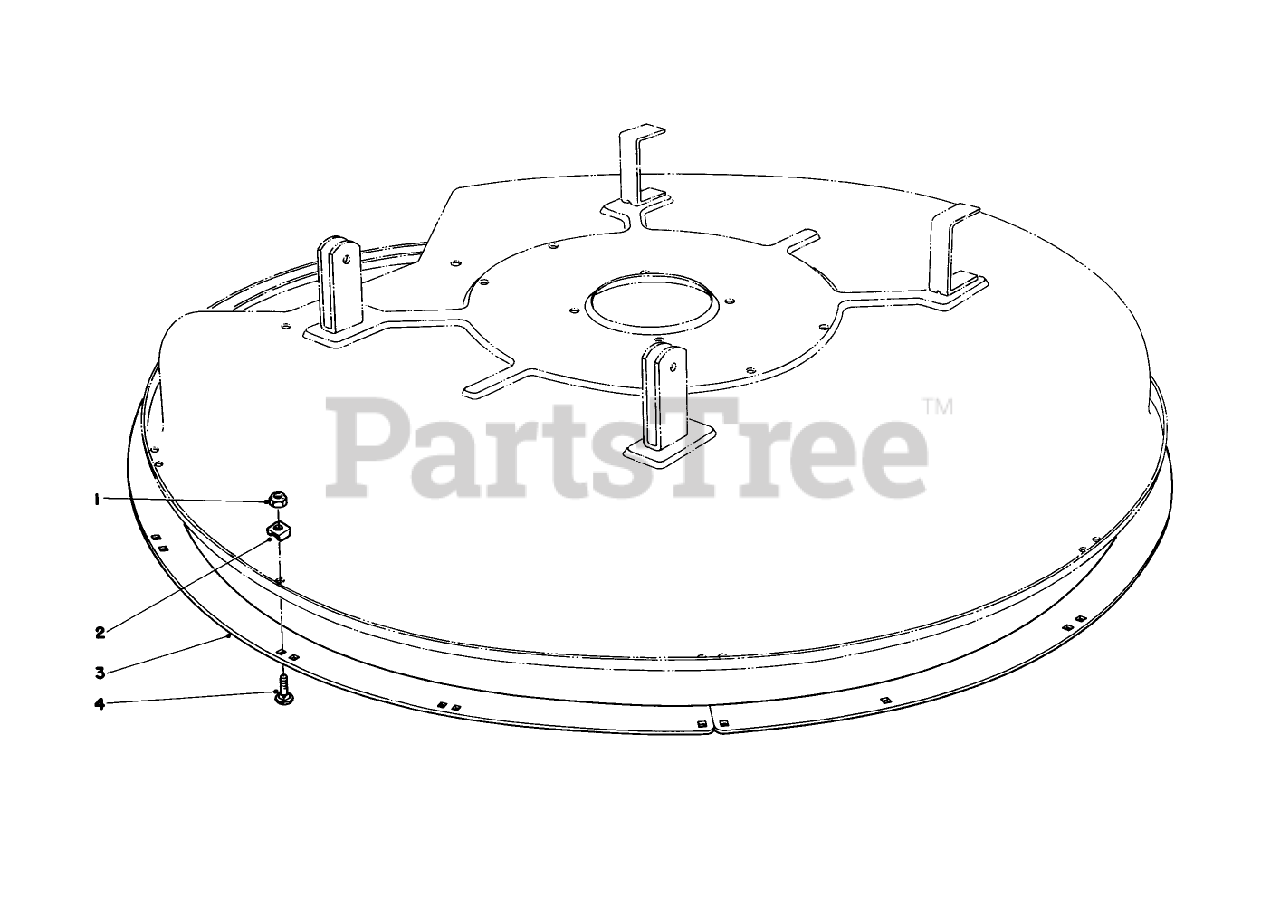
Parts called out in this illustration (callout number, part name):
1	NUT-LOCK, NI
3	DECK RING *B
4	BOLT-CARR
